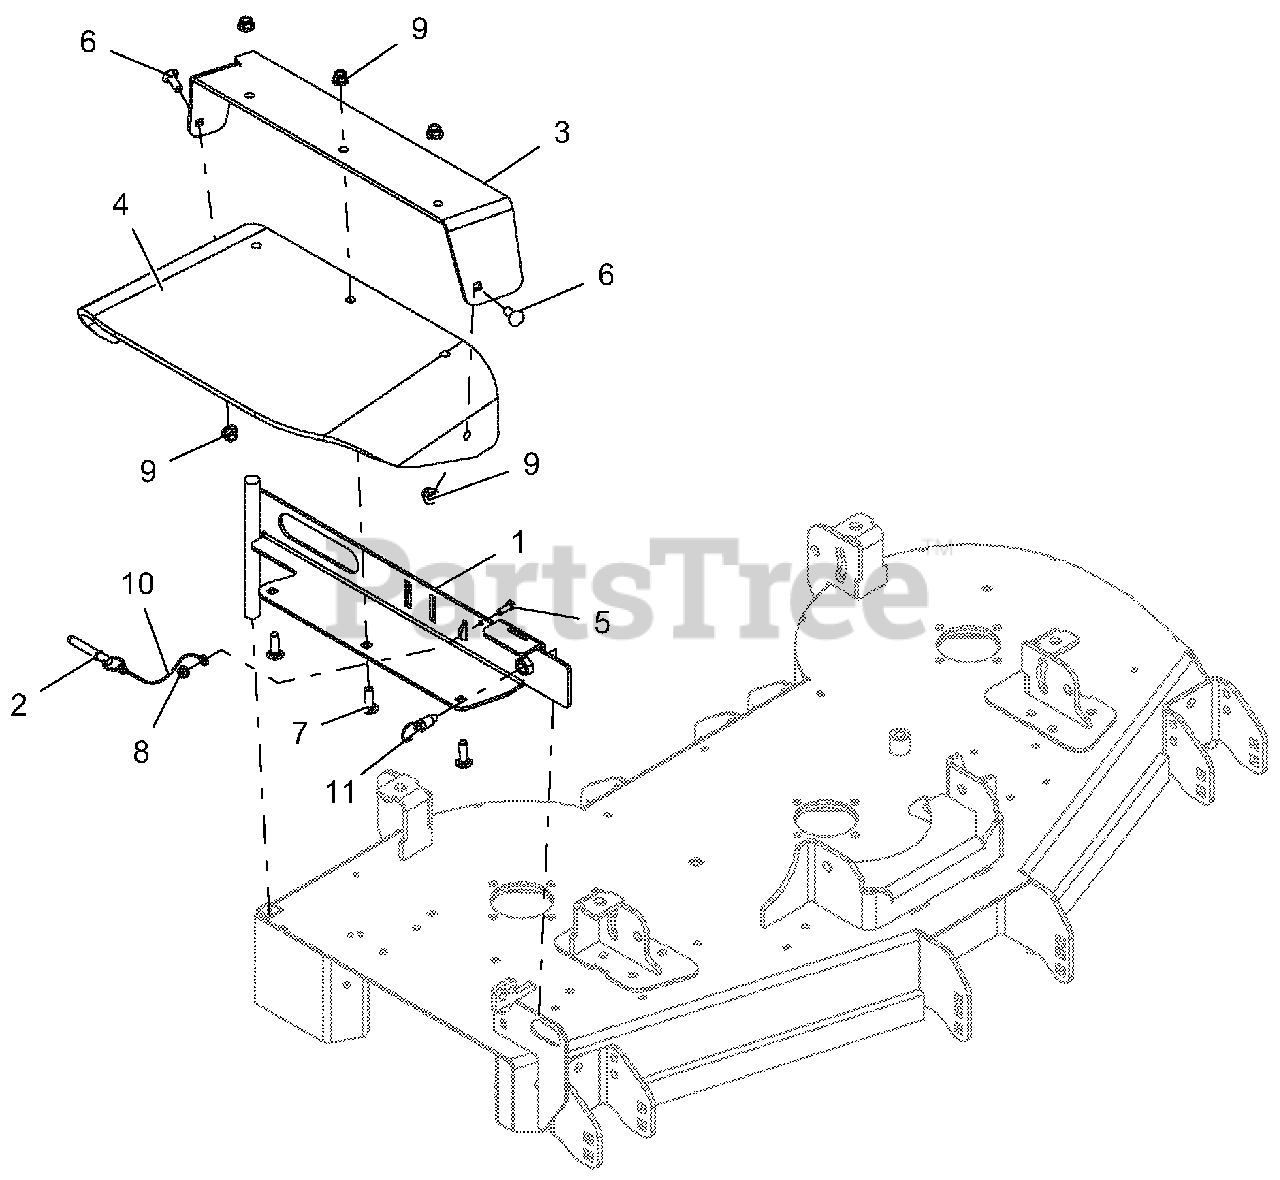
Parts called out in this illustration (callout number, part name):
1	WLDMT, 44"-48" DISCH CHUTE MTG-RED
2	PIN, SPRING BALL .375 OD X 1.50
3	DISCHARGE CHUTE SUPPORT W/SAFETY DECAL-RED
4	CHUTE, RUBBER DISCHARGE
5	BLT-HEX .25-20X.75 GR5 YWZC
6	BLT-RDHDSQNK .38-16X1.00 G5 YWZC
7	BLT-RDHDSQNK .38-16X1.25 G5 YWZC
8	NUT, LK-TOP-FLG .25-20 YWZC
9	NUT-LK-NYL-FLG .38-16 YWZC
10	CABLE, 6.0 LANYARD, NYLON
11	PULL PIN,.50-13THDX.310 PLNGR
